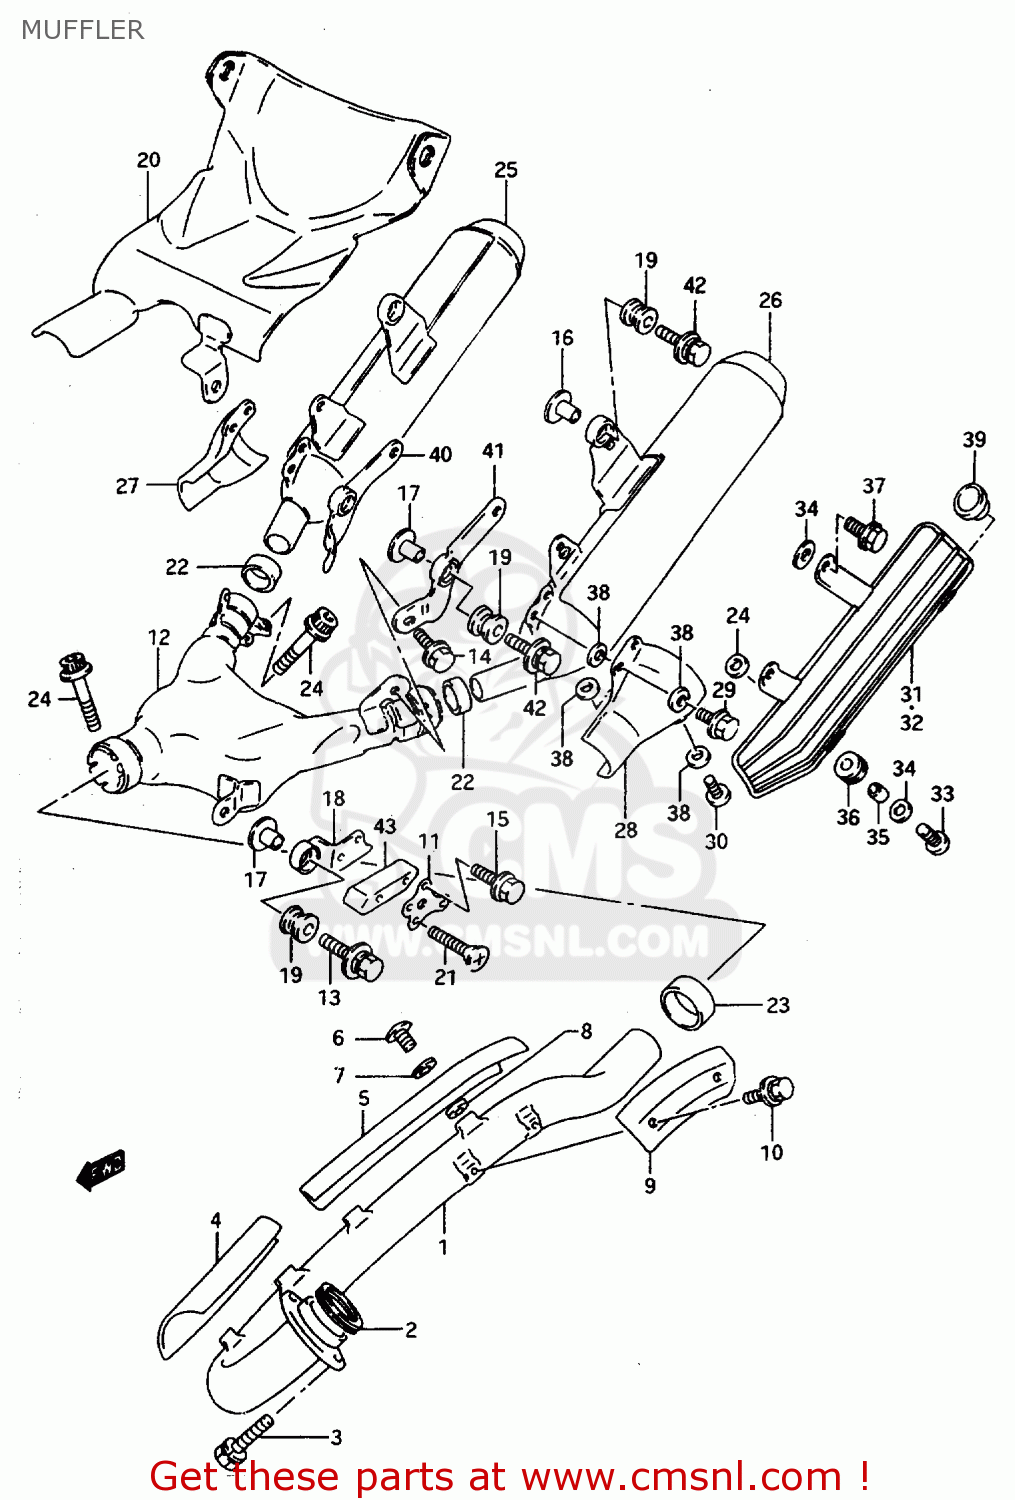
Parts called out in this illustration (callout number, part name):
1	PIPE,EXHAUST
2	GASKET,EXHAUST PIPE (NAS)
3	BOLT
4	COVER,EXHAUST PIPE
5	COVER,EXHAUST PIPE
6	SCREW(6X10)
7	WASHER(6.5X13X1.0)
8	GASKET(5.8X13X1.8) (NAS)
9	PLATE,HEAT GUARD
10	BOLT
11	PLATE,MANF GUARD
12	BODY,MANF
13	BOLT(8X40)
14	BOLT (10X20)
15	BOLT
16	SPACER(8.6X12X17.5)
17	SPACER(8.6X12X20)
18	BRACKET,MANIFOLD SUPPORT
19	CUSHION
20	GUARD,MANF HEAT
21	SCREW
22	CONNECTOR,MUFFLER
23	CONNECTOR,MUFFLER
24	BOLT(8X40)
25	MUFFLER,R
26	MUFFLER,L
27	COVER,MUFFLER FR,R
28	COVER,MUFFLER FR,L
29	BOLT
30	SCREW(6X10)
31	GUARD,LEG,R
32	GUARD,LEG,L
33	SCREW(6X16)
34	WASHER(6.5X18X1)
35	SPACER(6.5X9X9)
36	CUSHION
37	BOLT
38	GASKET(5.8X13X1.8) (NAS)
39	CUSHION
40	BRACKET, MUFFLER SUPPORT RH
41	BRACKET,MUFFLER SUPPORT
42	BOLT(8X40)
43	DEFENSE,CHAIN GUIDE
